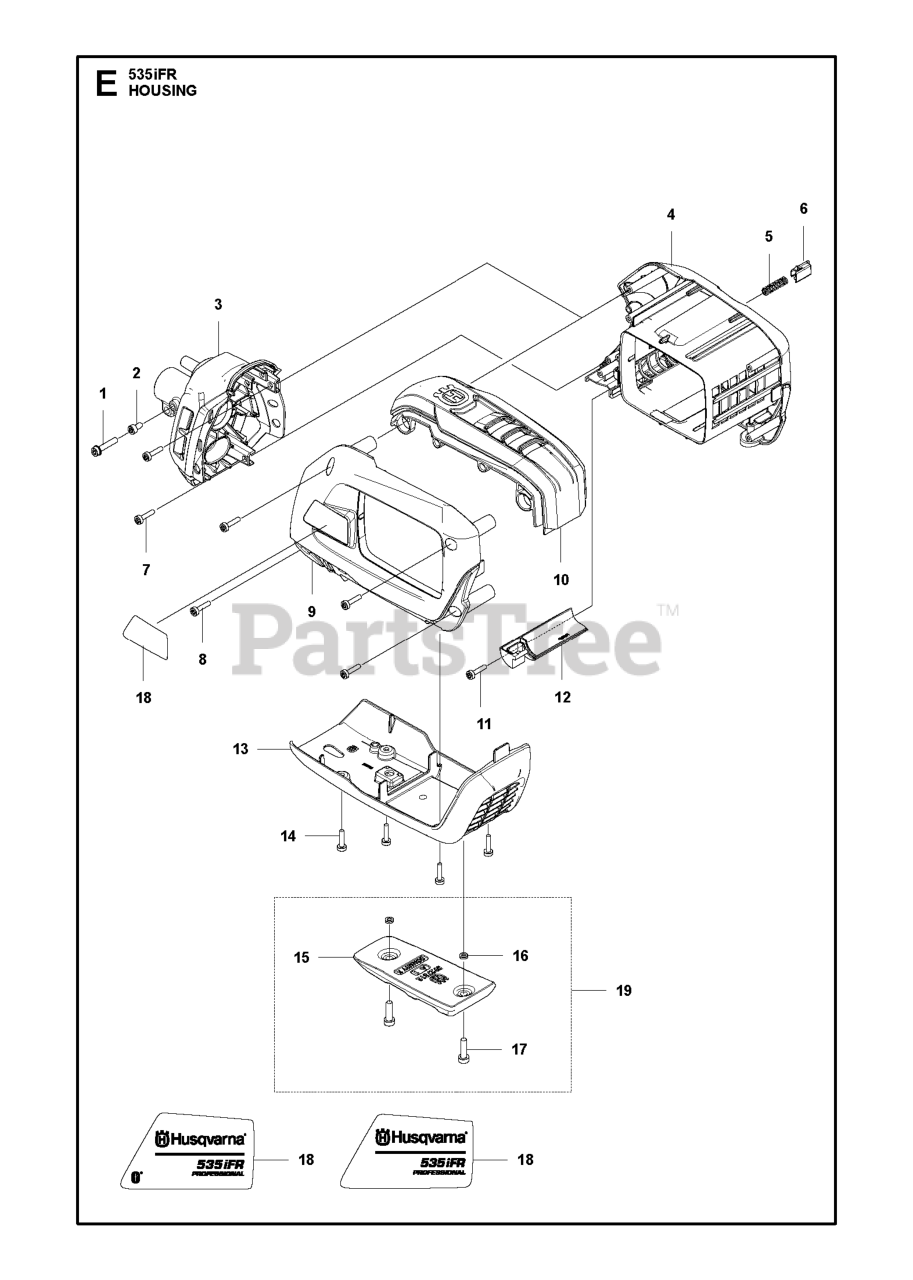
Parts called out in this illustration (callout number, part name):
5	SPRING PUSH OUT
6	PUSH BUTTON
7	SCREW ITXSCT PW4.2X18 10.9 ZN
8	SCREW ITXSCT PW4.2X18 10.9 ZN
11	SCREW ITXSCT PW4.2X18 10.9 ZN
12	AIR CONDUCTORS
13	SKID PLATES
14	SCREW ITXSCT PW4.2X18 10.9 ZN
16	LOCKING NUT M6
17	SCREW ITXSCM
18	DECALS
